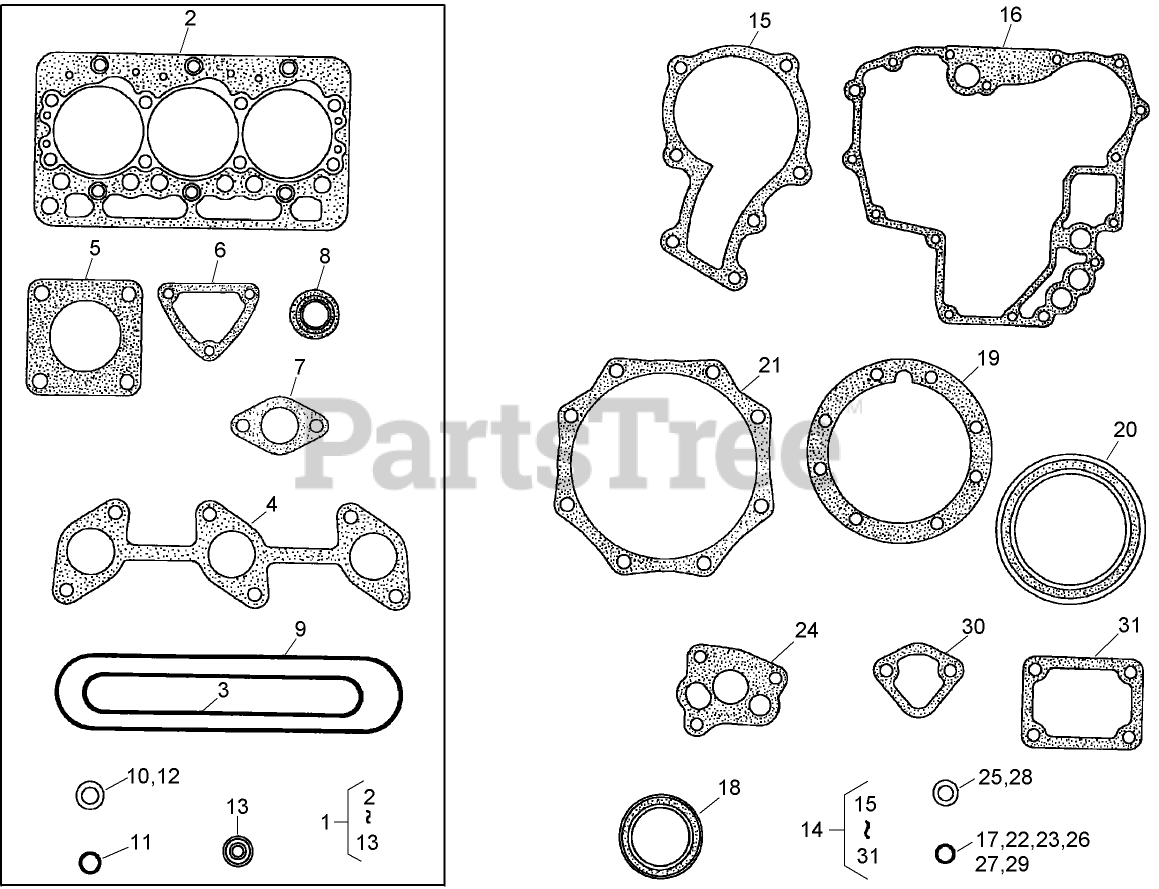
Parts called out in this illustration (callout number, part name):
1	UPPER GASKET KIT
2	GASKET-HEAD, CYLINDER
3	GASKET-MANIFOLD, INTAKE
4	GASKET-MANIFOLD, EXHAUST
5	GASKET-MUFFLER
6	GASKET-FLANGE, WATER
7	GASKET
8	SEAL-STEM, VALVE
9	GASKET-COVER, HEAD
10	O RING-BREATHER
11	O-RING
12	GASKET
13	SEAL-HEAT
14	LOWER GASKET KIT
15	GASKET-PUMP, WATER
16	CASE-GEAR
17	O-RING
18	SEAL-OIL
19	GASKET-CASE, BEARING
20	SEAL-OIL
21	GASKET-COVER, CASE
22	O-RING
23	O-RING
24	GASKET-PUMP, OIL
25	GASKET
26	O-RING
27	O-RING
28	GASKET
29	O-RING
30	GASKET-PUMP, FUEL
31	GASKET-PLATE, CONTROL
